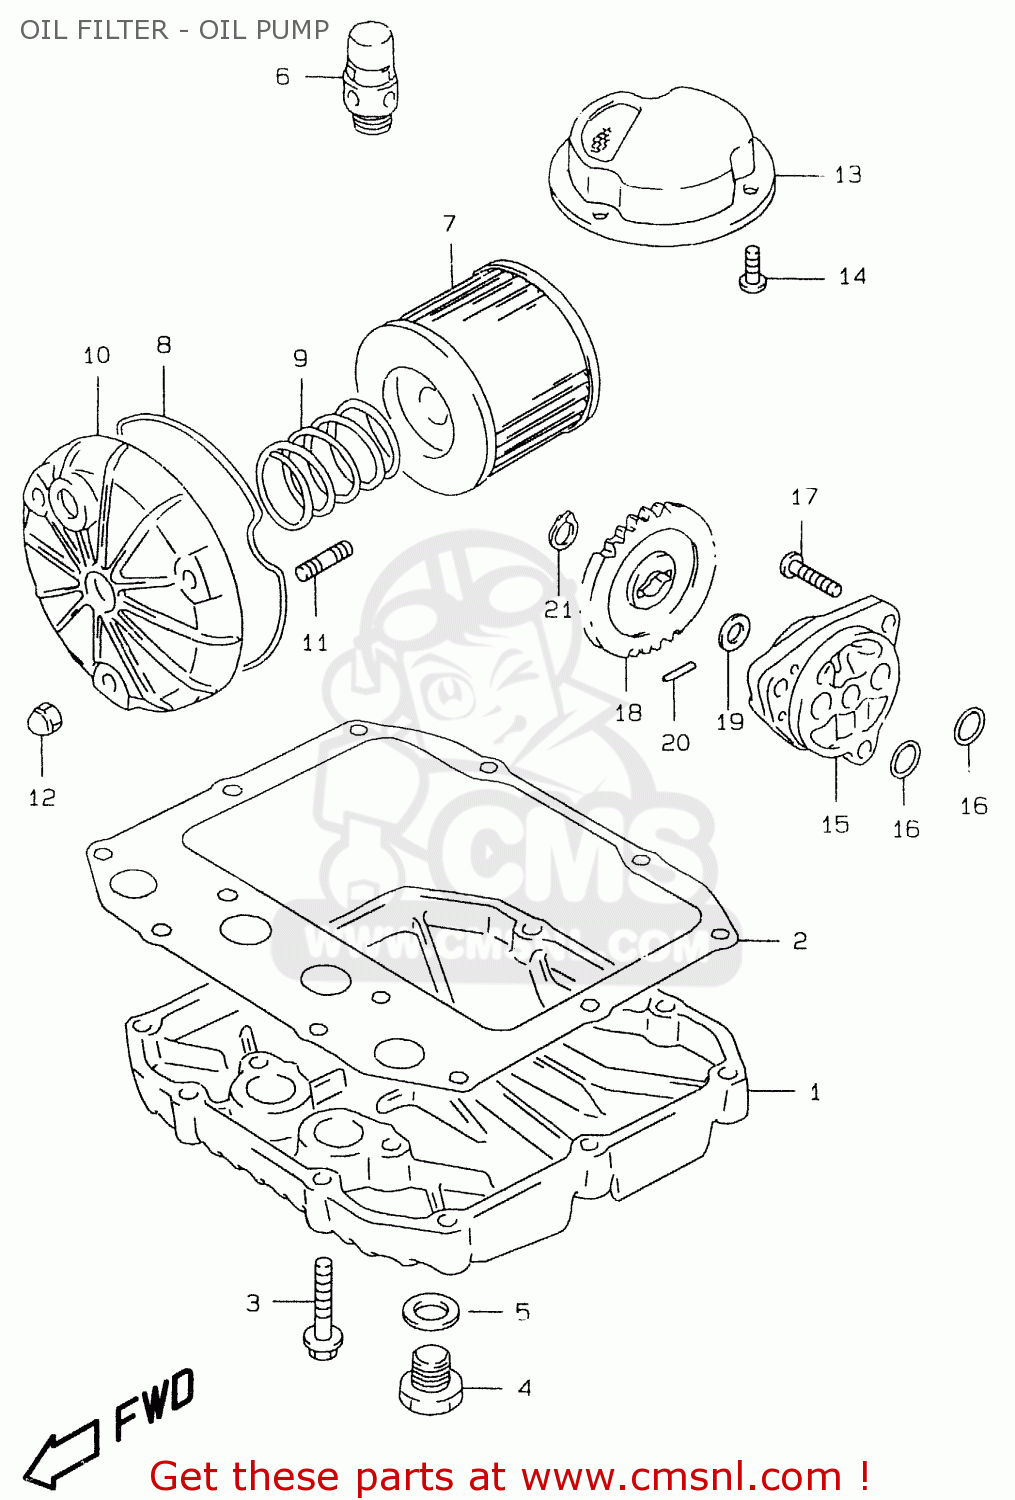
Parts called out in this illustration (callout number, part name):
1	PAN,OIL
2	GASKET,OIL PAN(ASB) (NAS)
3	BOLT
4	PLUG(14X12)
5	GASKET(13.8X18.8X4.8) (NAS)
6	REGULATOR ASSEMBLY,ENGINE
7	FILTER ASSY,ENGINE OIL
8	O RING,OIL FILTER CHAMBER CAP
9	SPRING
10	CAP,OIL FILTER
11	STUD 6X20
12	NUT
13	STRAINER,ENGINE OIL
14	BOLT
15	PUMP ASSY,ENGINE OIL
16	O RING(D:1.9,ID:13)
17	SCREW
18	GEAR,OIL PUMP DRIVEN
19	SHIM
20	PIN(4X15.8)
21	CIRCLIP,10MM
